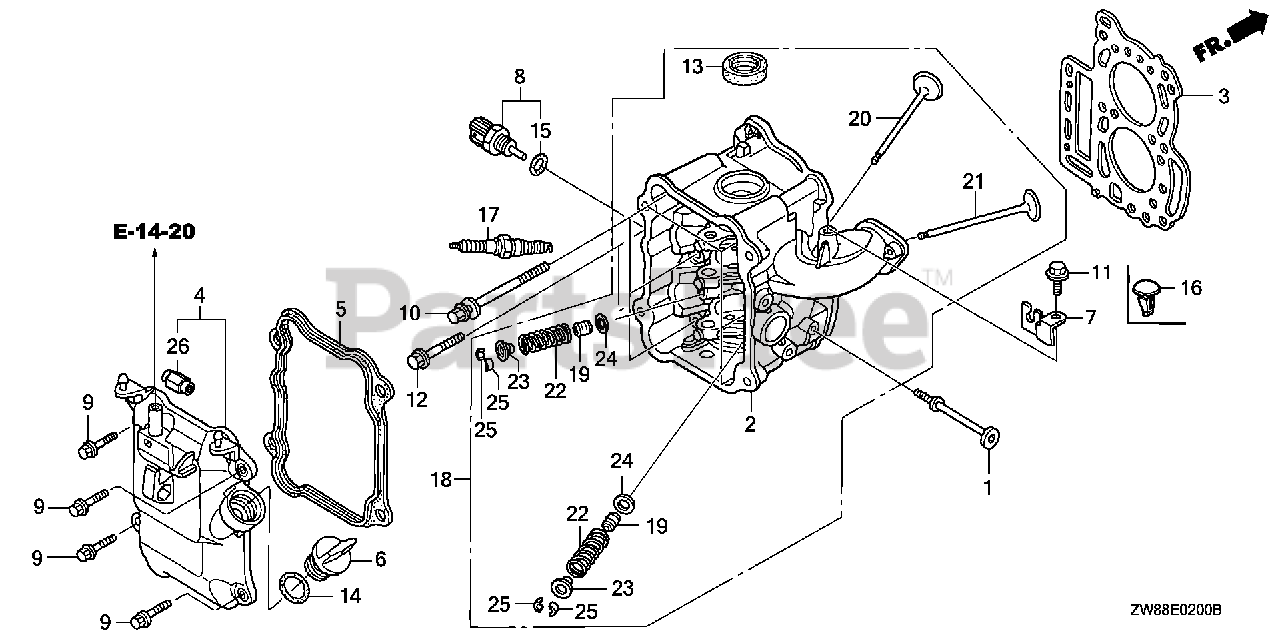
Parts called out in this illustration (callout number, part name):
1	STOPPER, ENGINE SIDE
2	CYLINDER HEAD *NH8* (DARK GRAY)
3	GASKET, CYLINDER HEAD
4	COVER, HEAD
5	GASKET, HEAD COVER
6	CAP, OIL (YELLOW)
8	SENSOR ASSY., WATER TEMPERATURE
9	BOLT, FLANGE (6X22)
10	BOLT, FLANGE (8X83)
12	BOLT, FLANGE (8X40)
13	OIL SEAL (20X32X6)
14	O-RING (26X2.7)
15	O-RING (9.5X1.5) (HONDA KIKAKI)
16	PLUG, HOLE (5.4MM)
17	SPARK PLUG (CR5EH-9)
17	SPARK PLUG (U16FER9)
18	CYLINDER HEAD ASSY. *NH8* (DARK GRAY)
19	SEAL, VALVE STEM (NOK)
20	VALVE, IN.
21	VALVE, EX.
22	SPRING, VALVE
23	RETAINER, VALVE SPRING
24	SEAT, VALVE SPRING
25	COTTER, VALVE
26	NUT, INSERT
